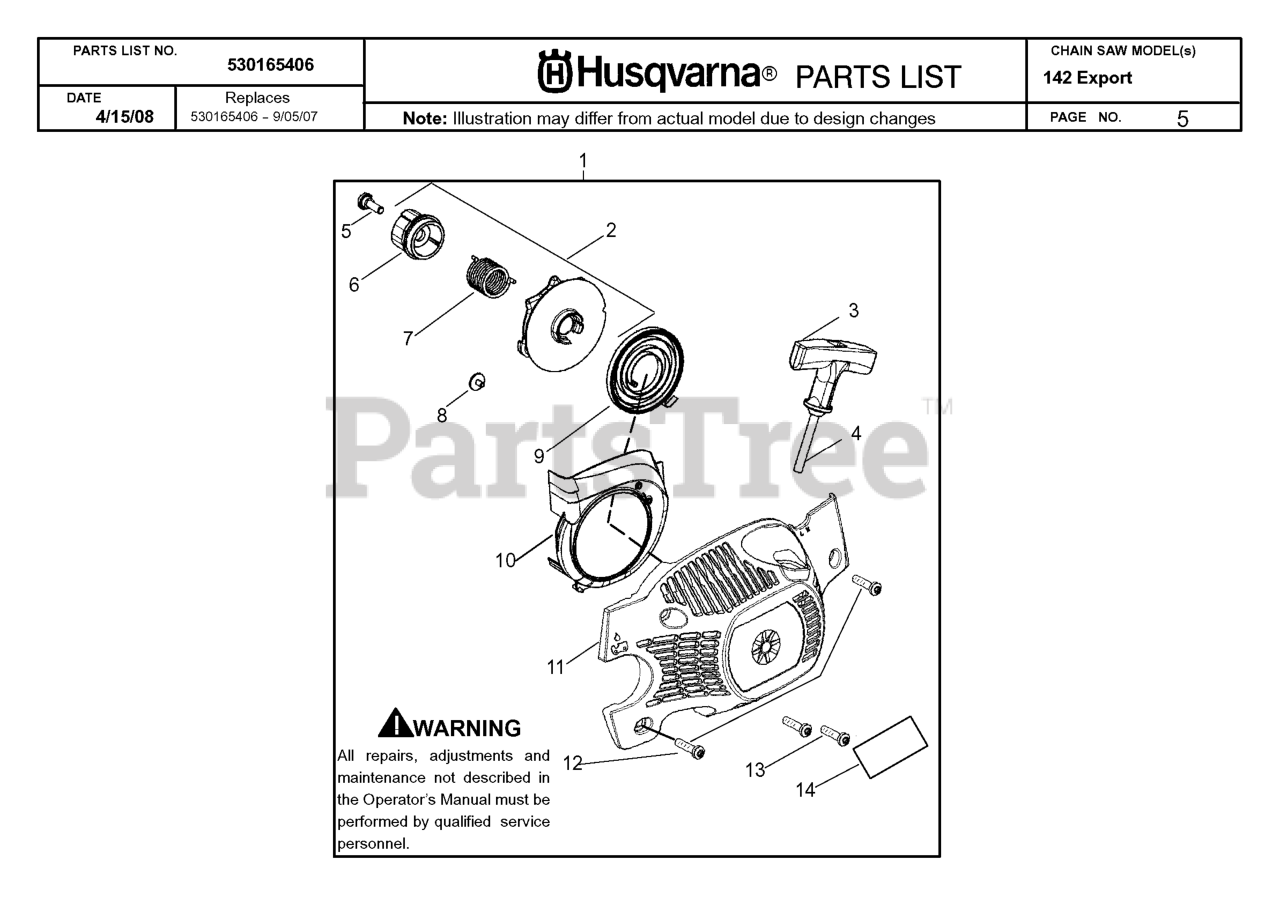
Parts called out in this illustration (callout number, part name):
1	KIT FAN HSG & STARTER EPS
2	KIT EPS STARTER
3	STARTER HANDLE GRAY
5	SCREW SHOULDER
6	HUB STARTER EPS
7	SPRING EPS
9	SPRING STARTER
10	BAFFLE AIR
11	HOUSING FAN W/ EYELET
13	SCREW,STRTR CVR 36/41
